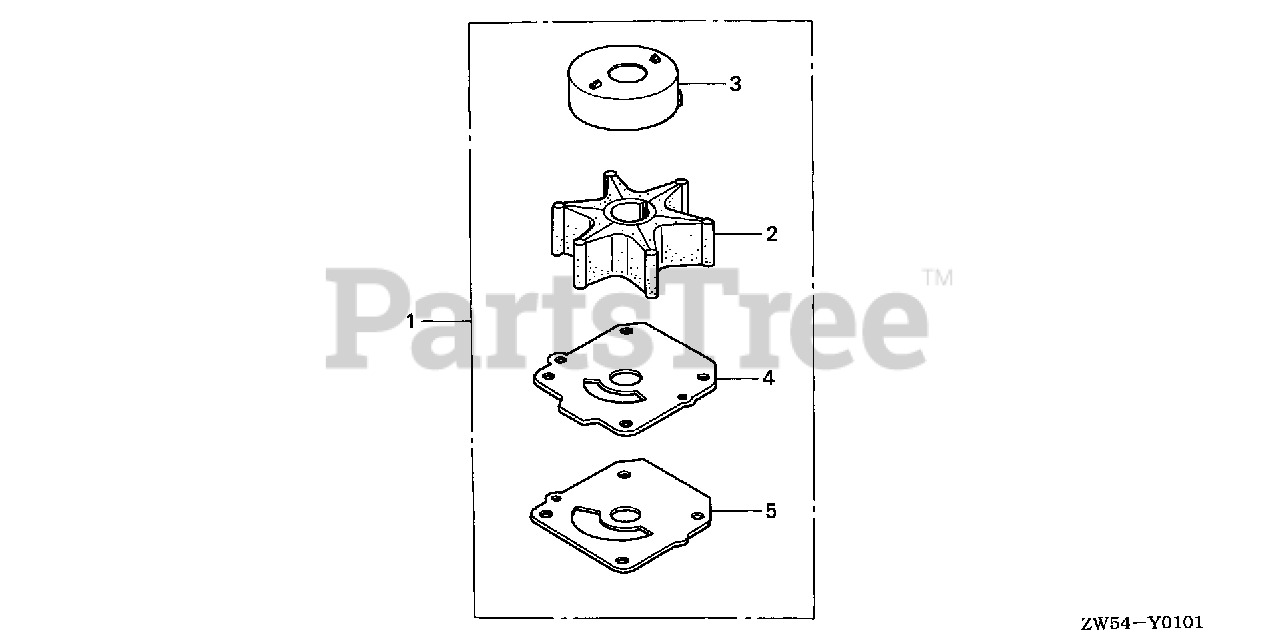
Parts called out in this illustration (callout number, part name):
1	PUMP KIT, IMPELLER
2	IMPELLER, PUMP
3	LINER, PUMP
4	COVER, IMPELLER
5	GASKET B, IMPELLER
